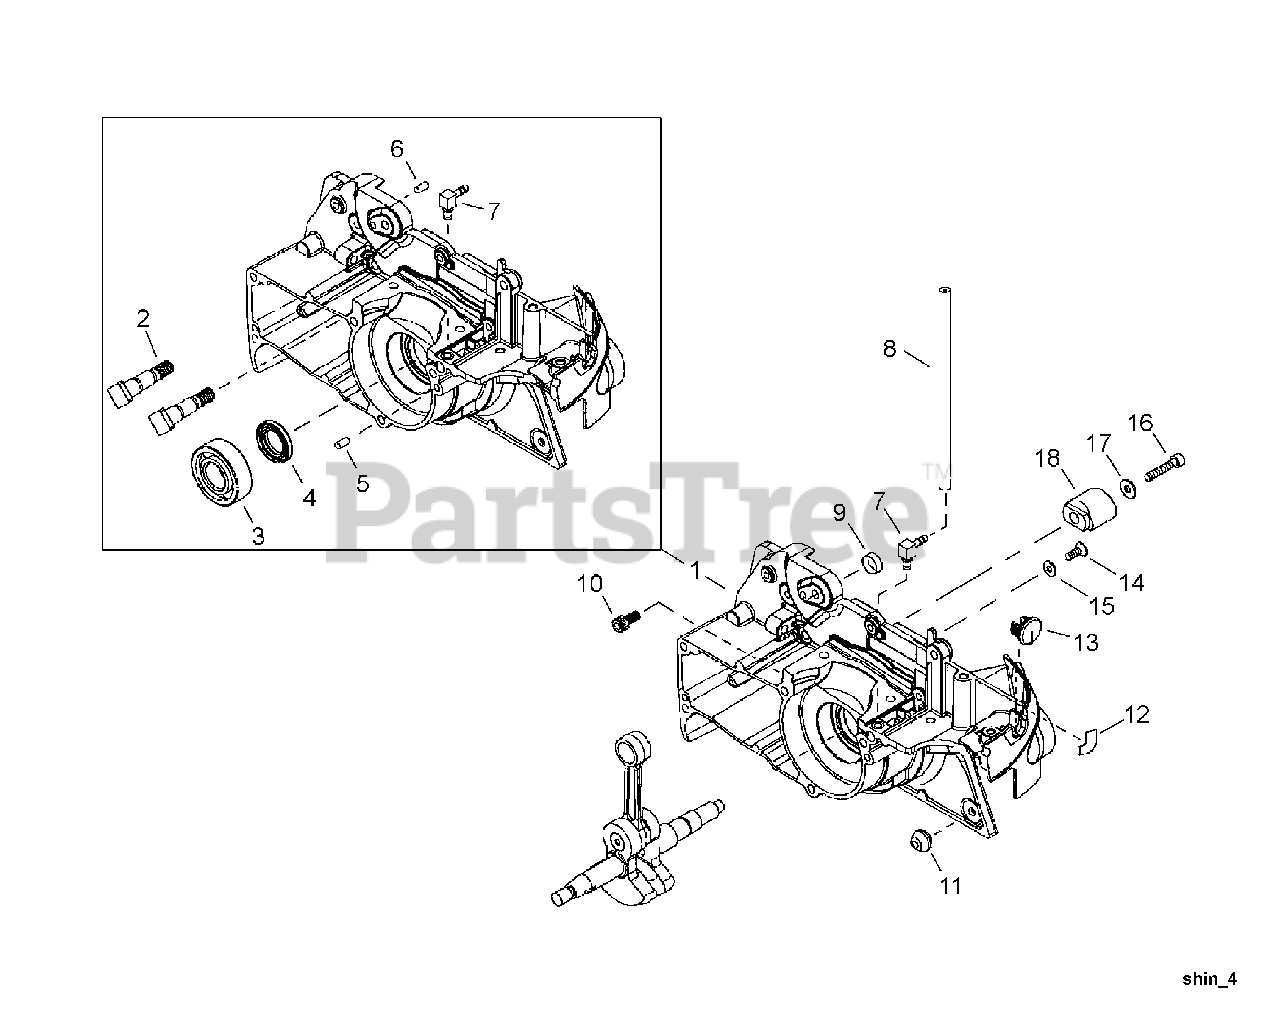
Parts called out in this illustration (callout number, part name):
1	CRANKCASE ASSY, C
2	BOLT, STUD 8
3	BEARING, BALL 6202C3
4	SEAL, OIL 15
5	PIN, LOCATING Ø4×8
6	PIN, LOCATING Ø4×11
7	CONNECTOR, PIPE
8	PIPE, PULSE
9	COLLAR 8
10	BOLT, ADHESIVE M5×12
11	CUSHION C
12	GROMMET, CHOKE
13	PLUG
14	SCREW 4×8
15	WASHER 4 MM
16	BOLT M5×25
17	WASHER, FLAT 5.5×10×0.8
18	CHAIN CATCHER
